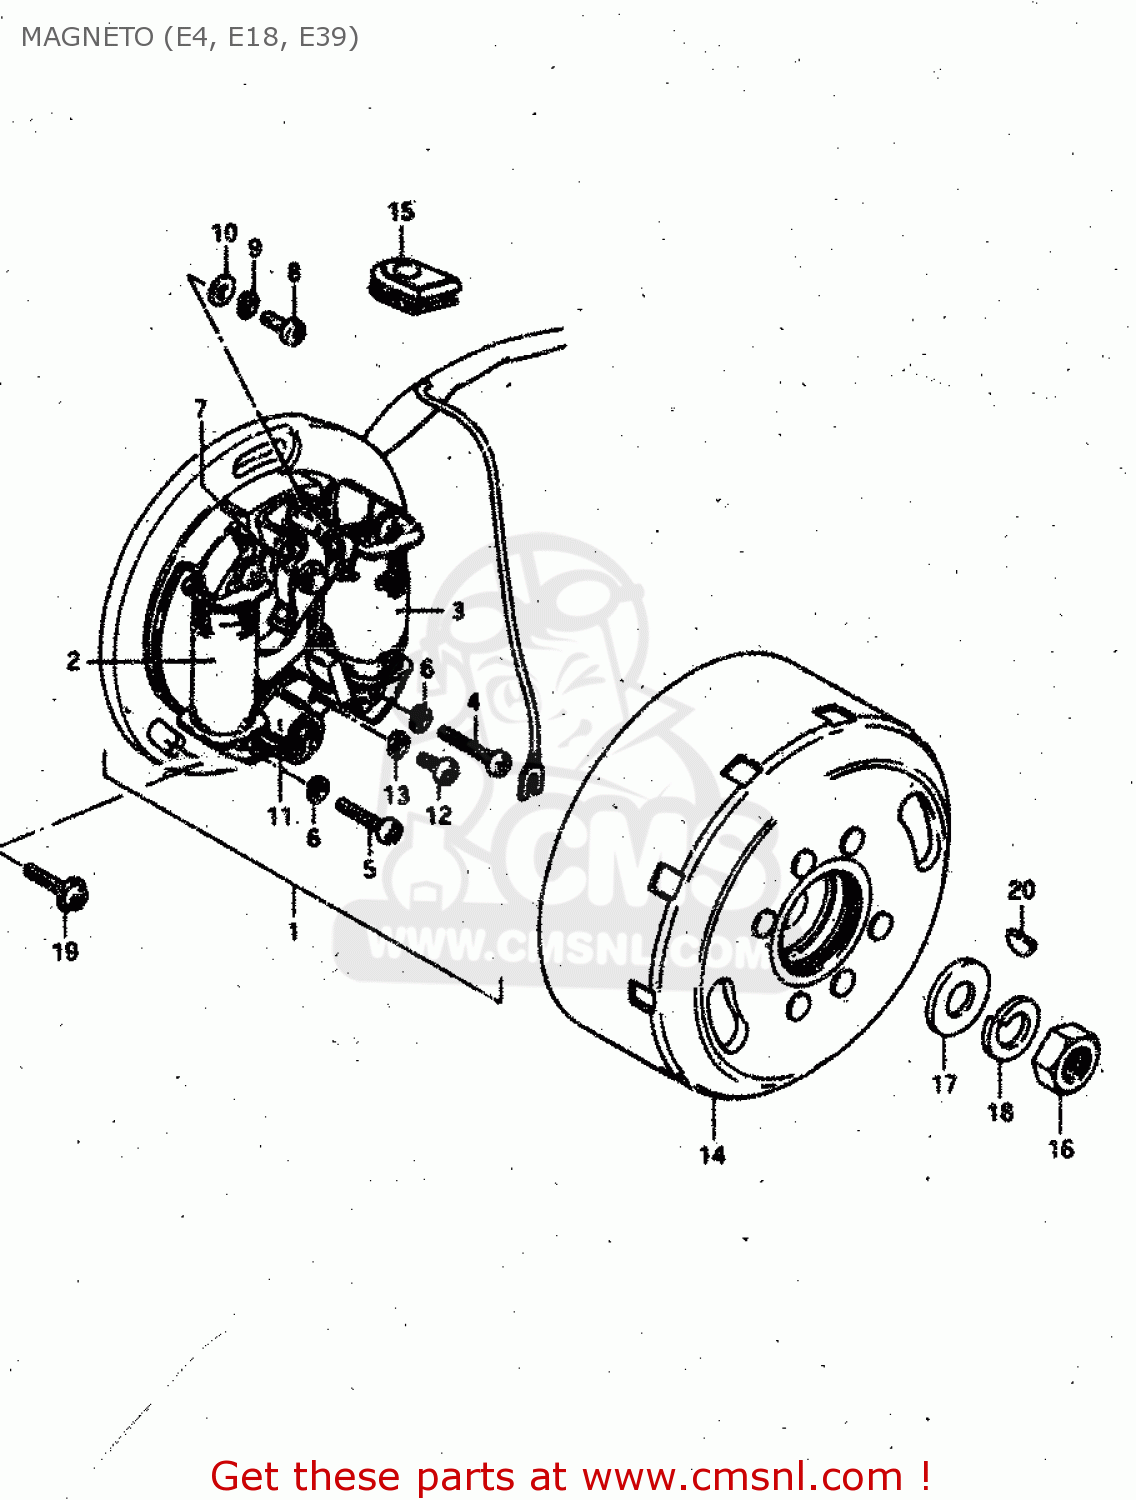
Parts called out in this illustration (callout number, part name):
1	STATOR ASSY
2	COIL, PRIMARY
3	COIL, LIGHTING
4	SCREW 4X25
5	SCREW
6	LOCK WASHER
7	POINT ASSY,CONTACT
8	SCREW(4X10)
9	LOCK WASHER
10	WASHER
11	CONDENSER
12	SCREW
13	LOCK WASHER
14	ROTOR
15	GROMMET
16	NUT (10MM)
17	WASHER
18	LOCK WASHER
19	SCREW(5X14)
20	KEY
